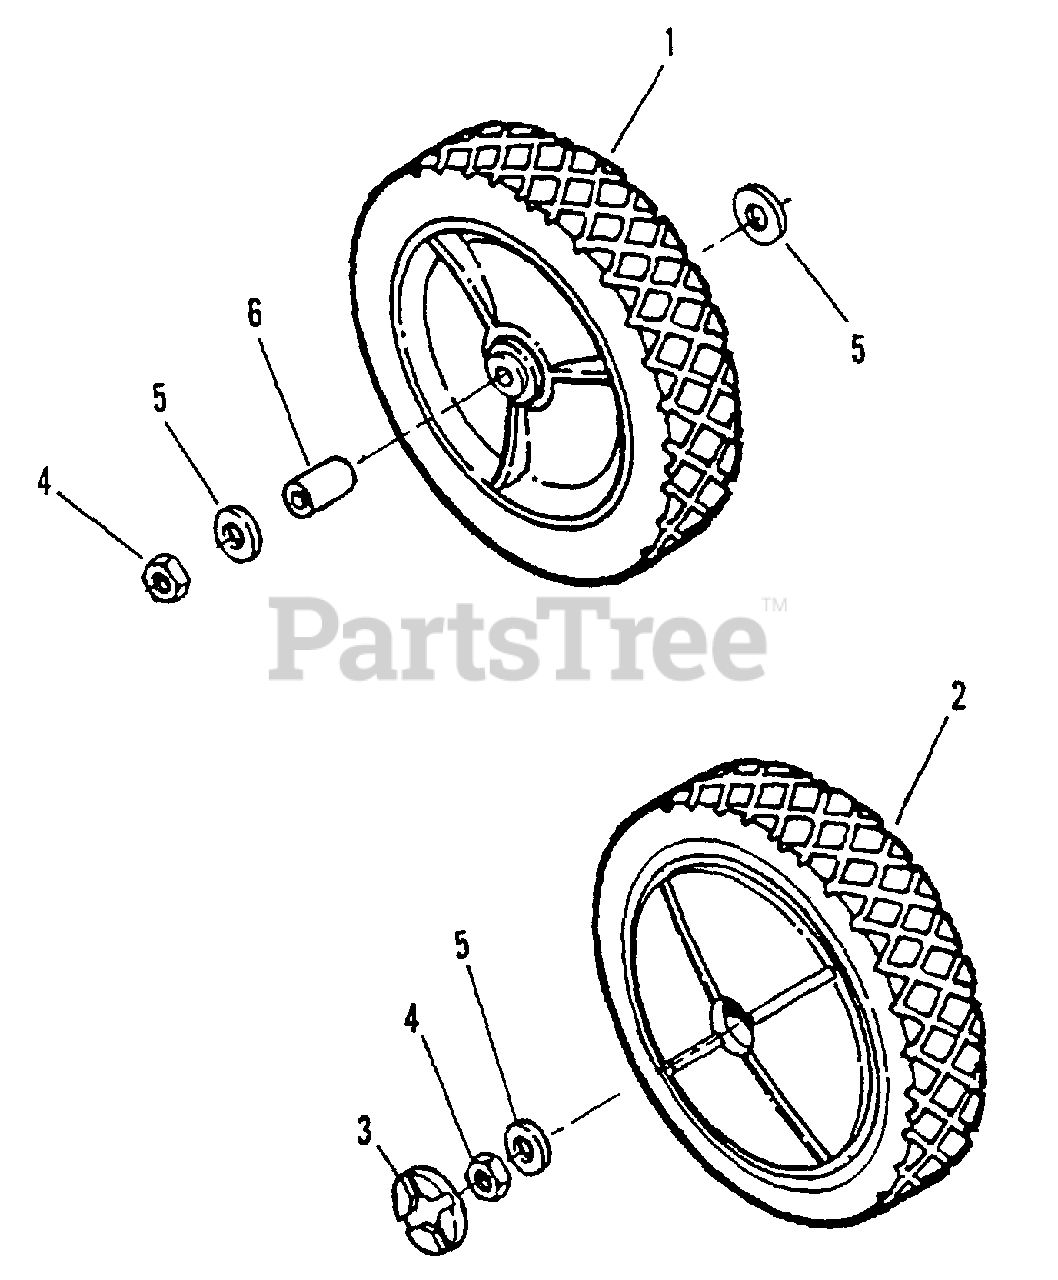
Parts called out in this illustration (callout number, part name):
1	WHEEL, 10 x 1.75 Plastic (Push)
2	WHEEL, 10 x 1.75 Plastic (Self-Prop)
3	PLUG, Wheel (Self-Prop)
4	NUT, 7/16-20 Hex (Thin)
5	WASHER, 7/16 x 1" O.D. Flat
6	BUSHING, Axle (Push)
